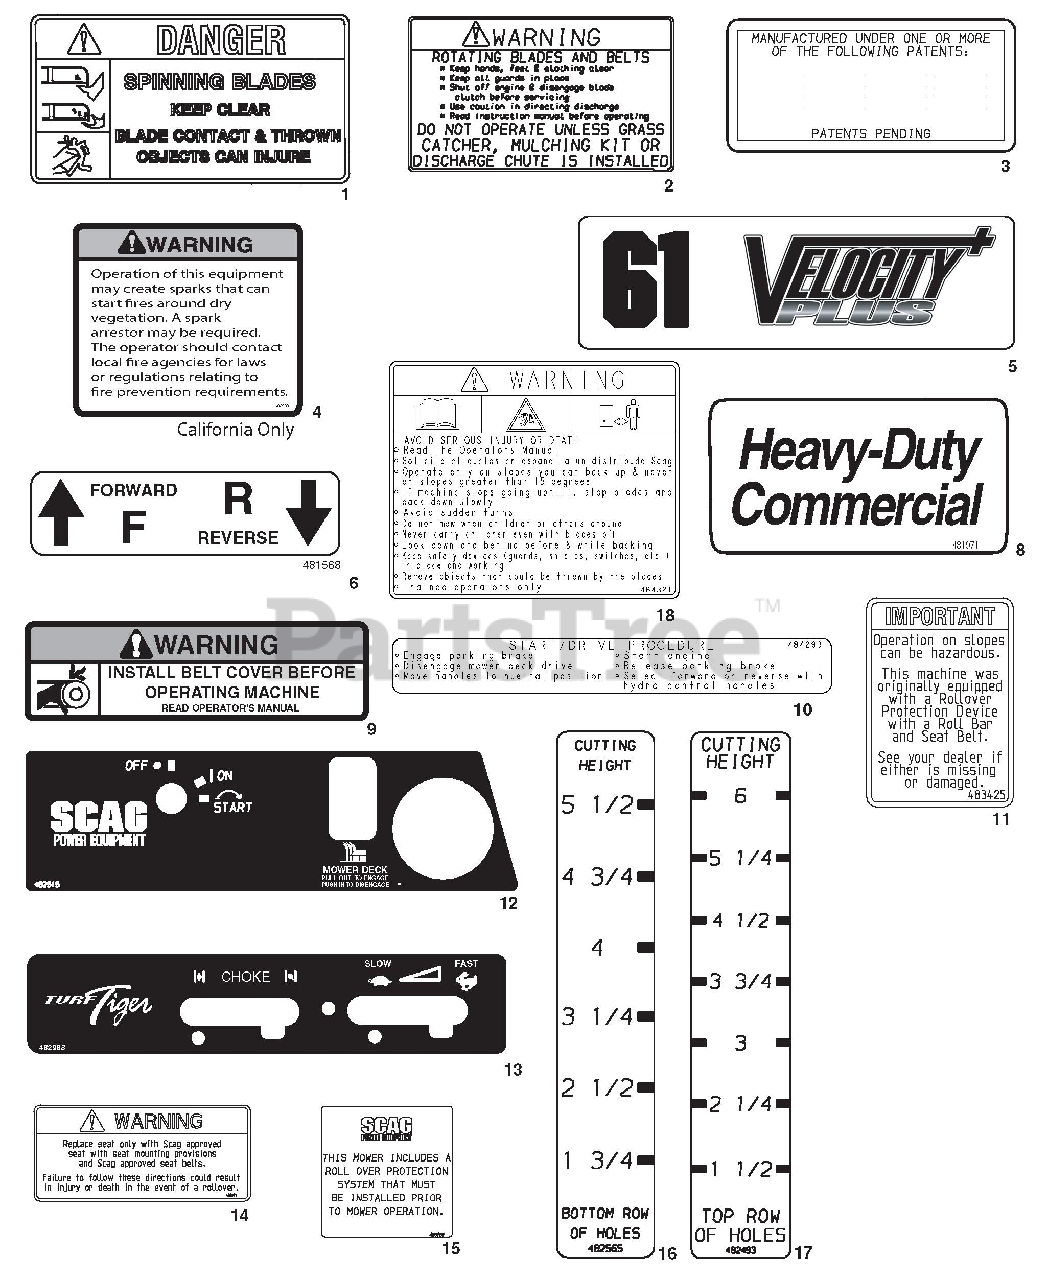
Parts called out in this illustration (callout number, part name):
1	Decal, Danger-Spinning Blades
2	Decal, Warning-Rotating Blades
3	Decal, Patents
4	Decal, Warning Spark Arrestor
5	Decal, 52" Velocity Plus
5	Decal, 61" Velocity Plus
6	Decal, Traction Control
8	Decal, Heavy Duty Commercial
9	Decal, Belt Cover
10	Decal, Start / Drive
11	Decal, ROPS
12	Decal, Instrument Panel - Upper
13	Decal, Instrument Panel - Lower
14	Decal, Seat Replacement
15	Decal, ROPS
16	Decal, Cutting Height - Lower
17	Decal, Cutting Height - Upper
18	Decal, Start/Drive Procedure
